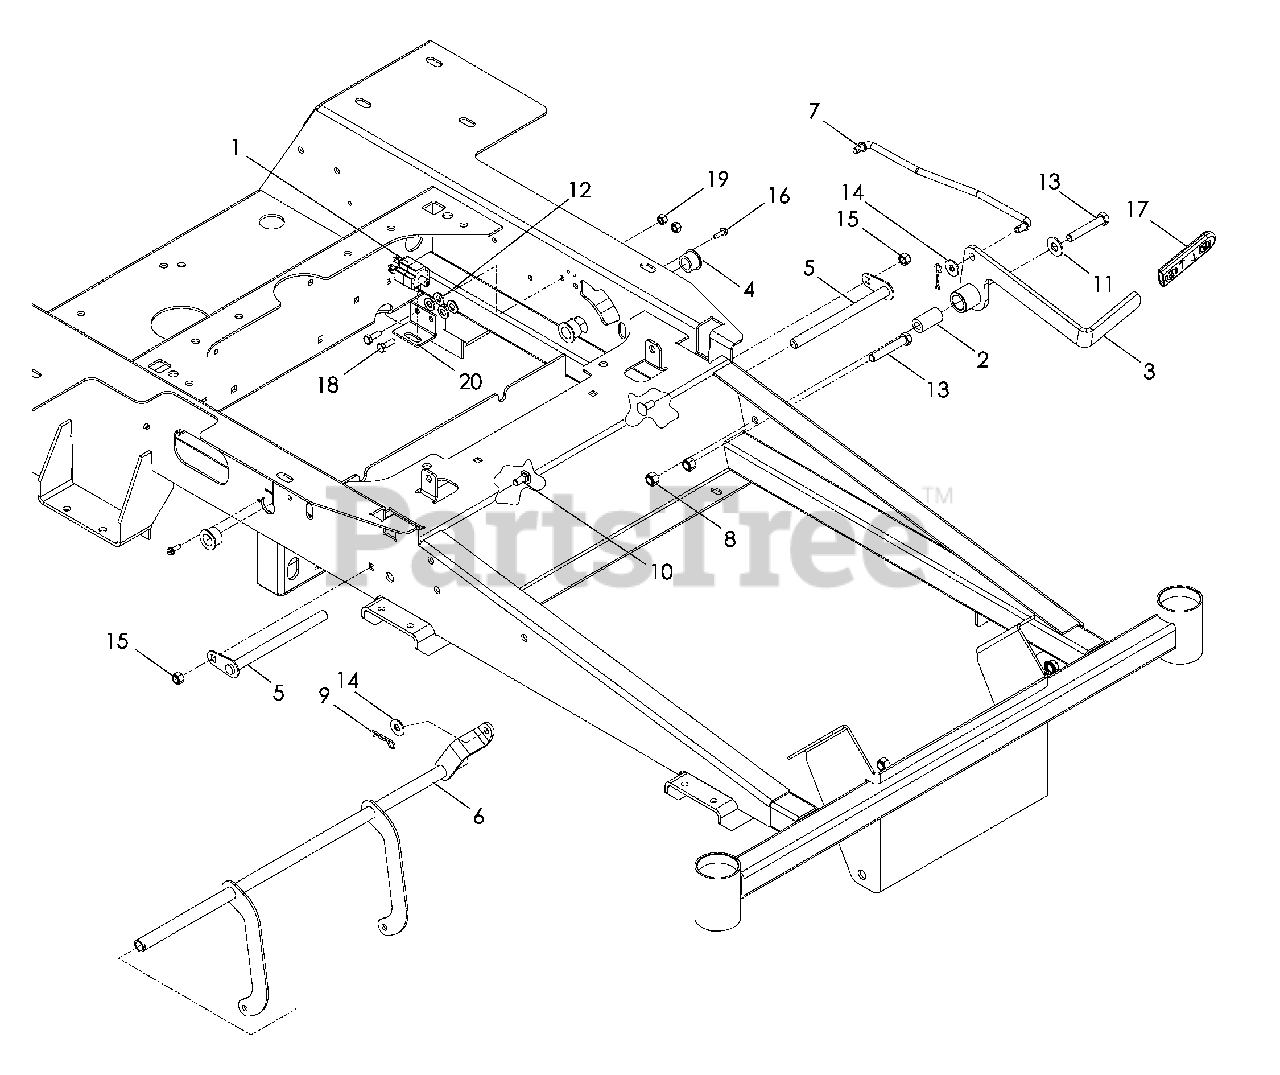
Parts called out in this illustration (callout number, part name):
1	SWITCH, BRAKE
3	BRAKE LEVER
4	BUSHING, PLASTIC
5	SHAFT, PIVOT
6	BRAKE SHAFT
8	NUT 3/8-16 NYLOC
9	PIN, HAIR .073 x 17/16
10	RHSNB 5/16-18 x ¾
11	WASHER 3/8
12	WASHER 5/16 SAE FLAT
13	HCS 3/8-16 x 2¼
14	WASHER 5/16
15	NUT 5/16-18 NYLOC
16	SCREW #10-24 x 5/8 WASH HD
17	GRIP, PARK BRAKE
18	HCS ¼-20 x ¾
19	NUT ¼-20 NYLOC
20	BRACKET, BRAKE SWITCH
